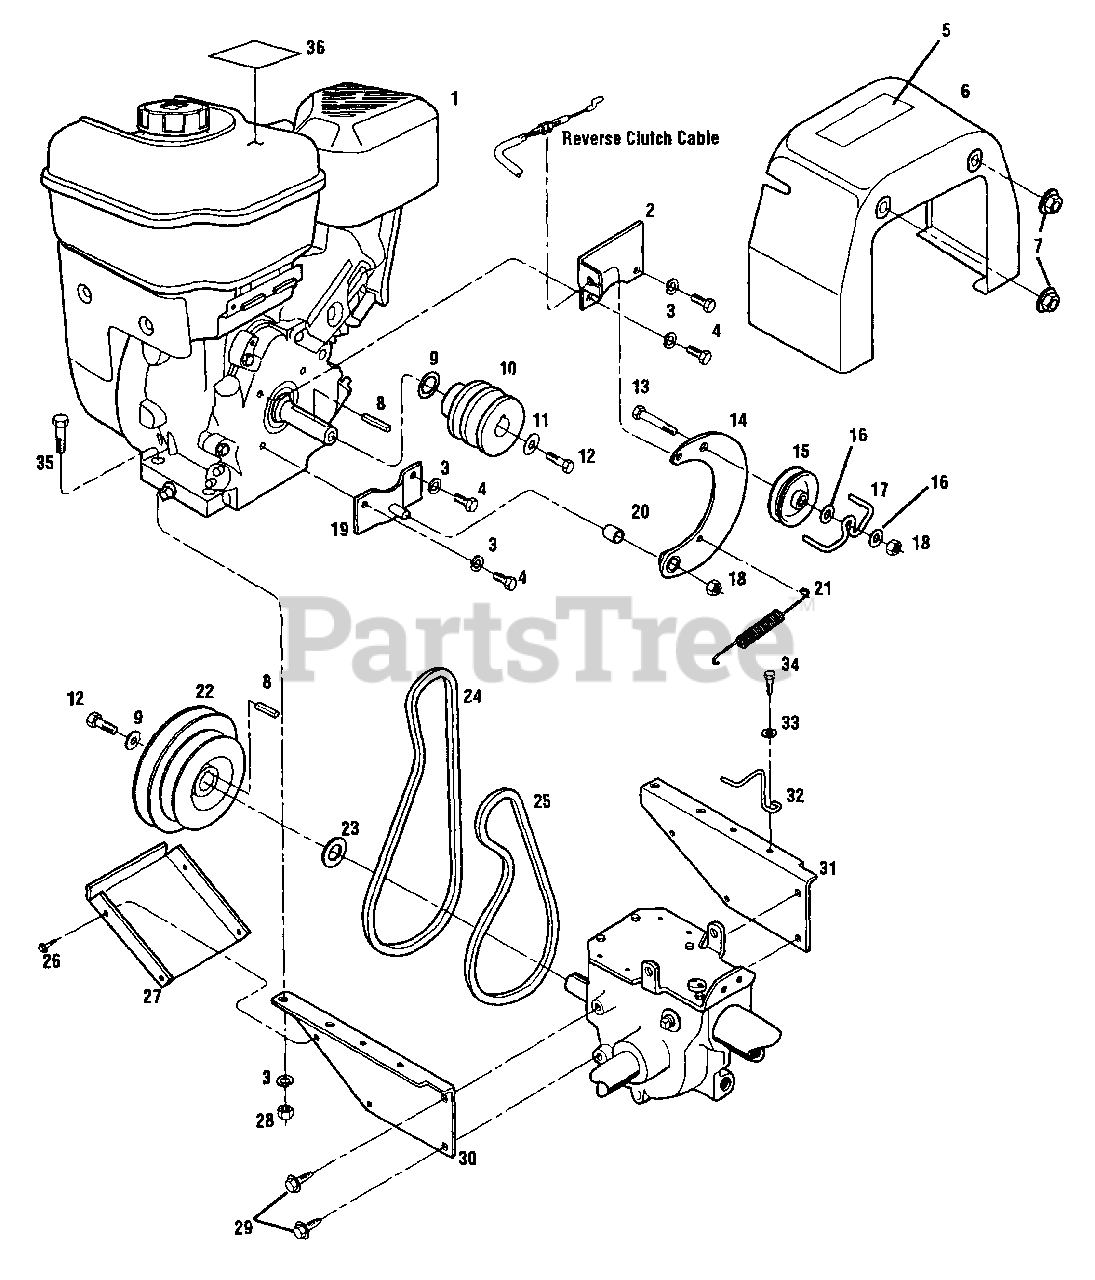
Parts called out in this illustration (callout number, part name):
1	Engine - 6HP, standard recoil start
2	Bracket, Clutch Cable
3	Lockwasher - 5/16
4	Screw-hex hd., 5/16-24 x 1/2
5	Decal-Hot surfaces/belt warning
6	Cover
7	Nut-5/16-18, Flange Lock
8	Key-3/16 x 1-1/2
9	Washer-Disc Spring
10	Pulley, Engine Drive
11	Washer, Belleville
12	Screw-hex hd., 5/16-24 x 1-1/8
13	Screw-hex hd., 5/16-18 x 2
14	Reverse Idler Arm
15	Pulley, Reverse Idler
16	Washer, Flat, 5/16
17	Belt Guide
18	Locknut, 5/16-18
19	Bracket, Reverse Idler
20	Bushing
21	Spring, Reverse Return
22	Pulley, Transmission
23	Support Washer
24	Reverse Drive Belt
25	Forward Drive Belt
26	Screw-hex hd., #10-32 x 1/2, self-tapping
27	Guard, Belts/Pulleys
28	Hex Nut, 5/16-18
29	Screw-flanged hex hd., 5/16-18 x 3/4
30	Support Bracket-engine, left side
31	Support Bracket-engine, right side
32	Belt Guide
33	Washer-flat, 1/4
34	Screw-hex hd., self-tapping, 1/4-20 x 3/4
35	Screw-hex hd., 5/16-18 x 1-1/2
36	Decal-Stabilization
